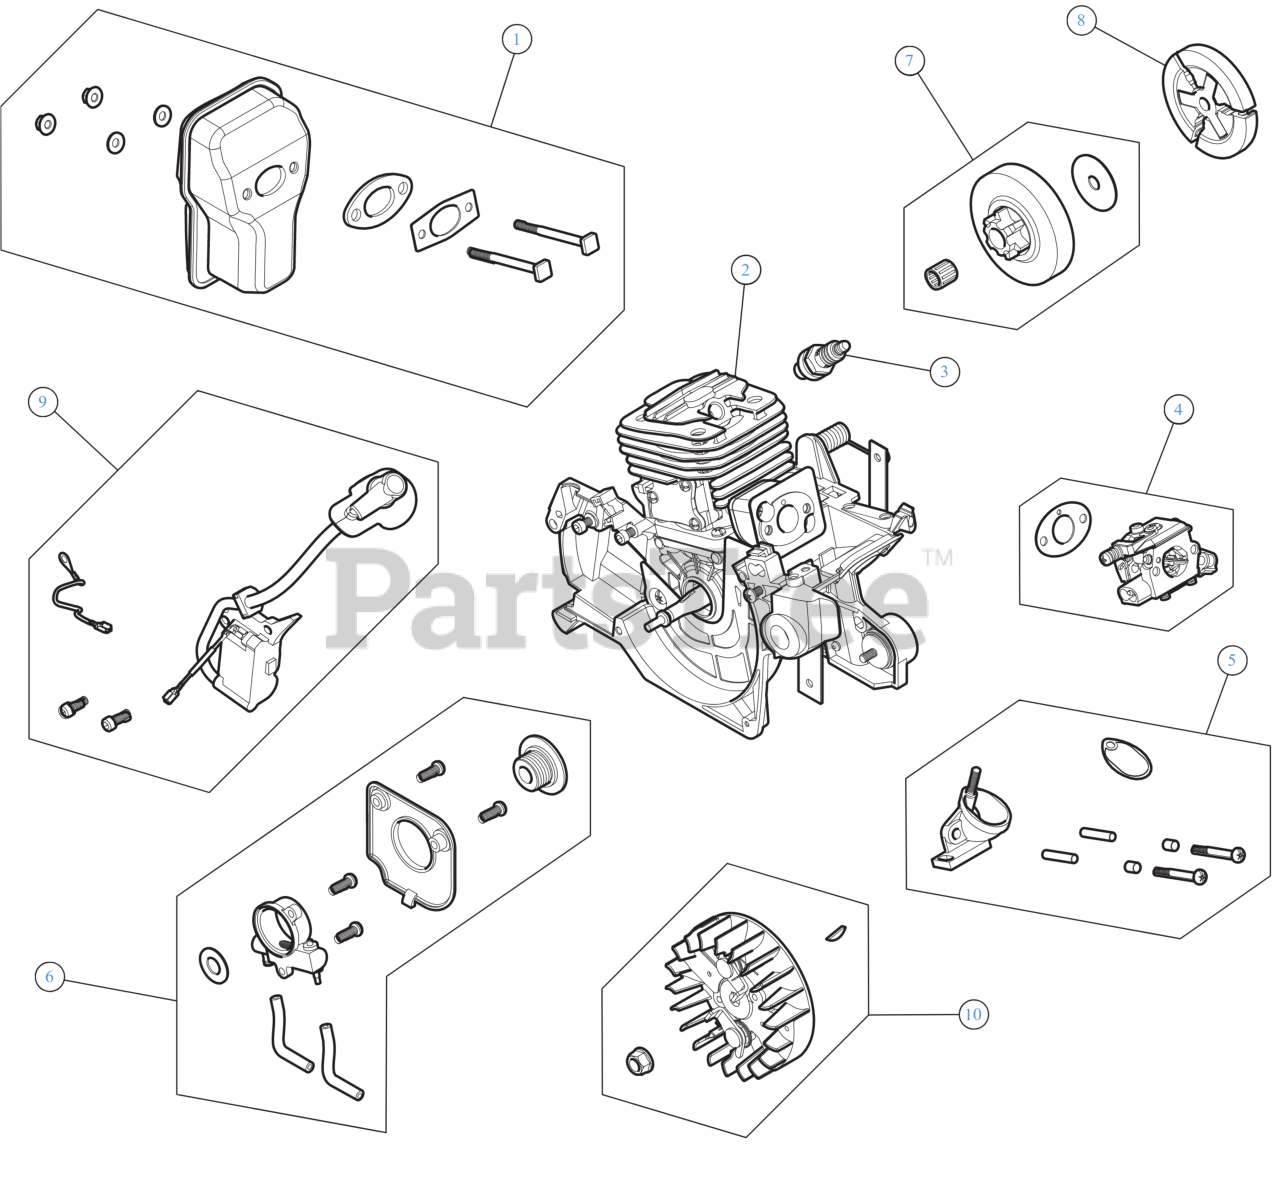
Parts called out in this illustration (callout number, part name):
1	MUFFLER
2	42CC SHORT BLOCK
3	SPARK PLUG
4	CARBURETOR
5	CARBURETOR HARDWARE
6	OIL PUMP
7	CLUTCH DRUM
8	CLUTCH
9	MODULE
10	FLYWHEEL
